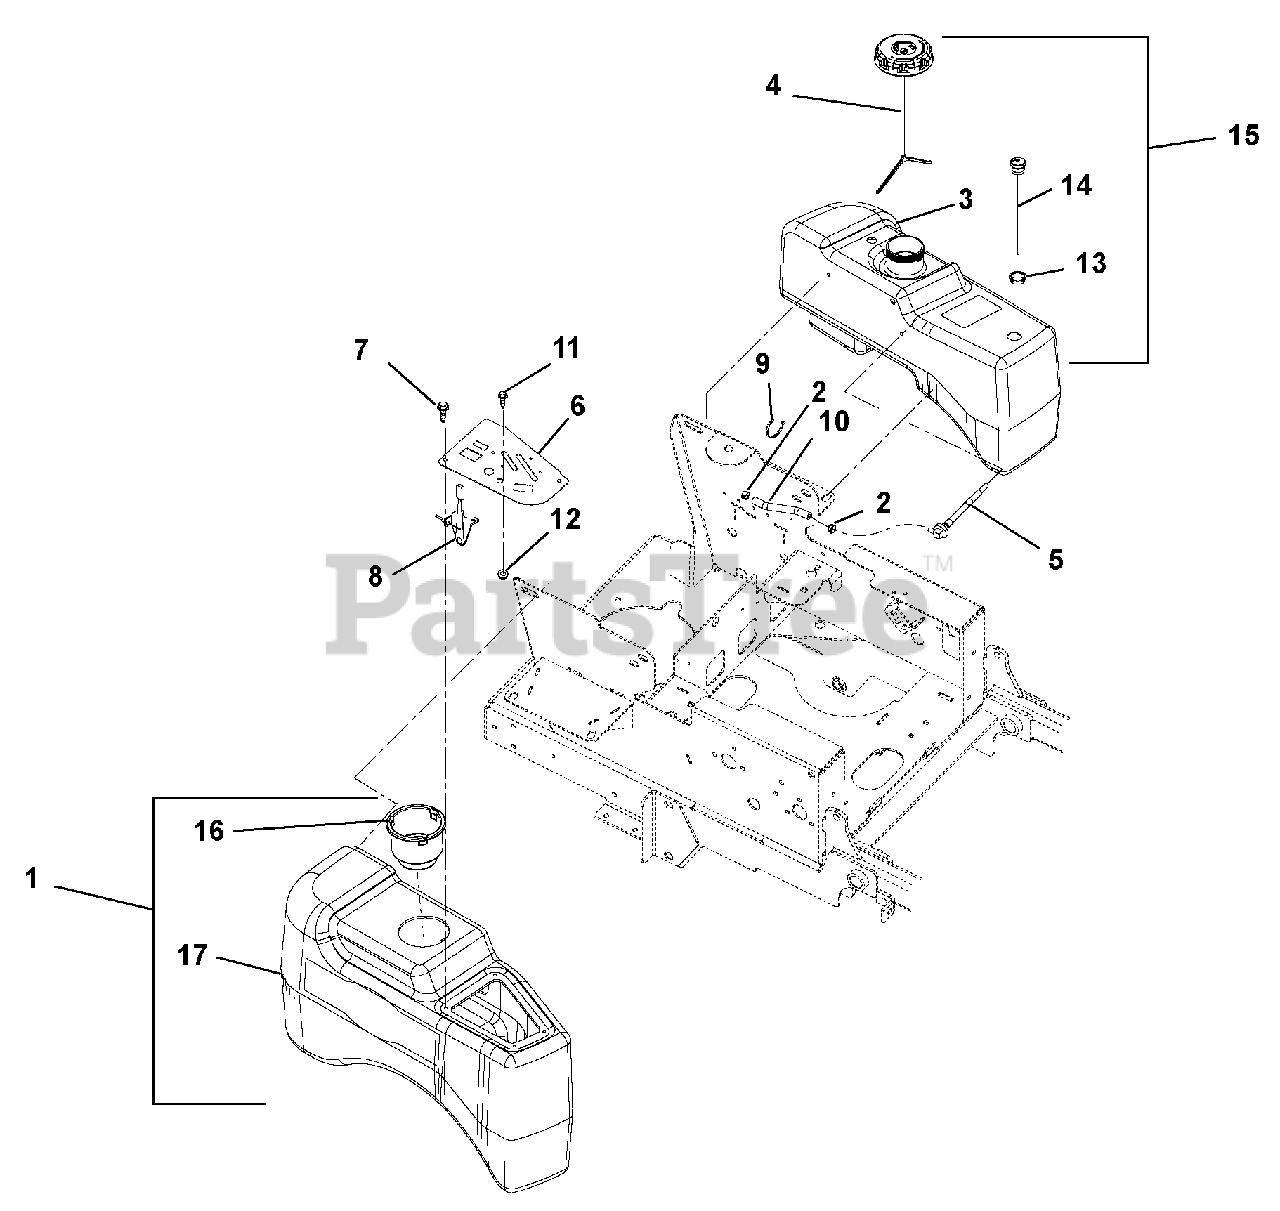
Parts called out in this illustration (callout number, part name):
1	Assembly, Fender with Cupholder (Includes items 16 and 17)
2	Clamp, Fuel Line
3	Tank, Fuel Left Hand
4	Cap, Fuel Vent-in Autolock (991082, 083, 084, 090, 107, 108, 109, 110)
4	Cap, Fuel Non-Vent Autolock (991098, 099, 100, 101)
5	Assembly, Tank Fuel Pick-up
6	Panel, Control
7	Screw, Plastite .25 x 10 x .75 YZ
8	Cable, Control
9	Cable Tie
10	Hose, .25 Low-PERM Bulk Gas
11	Screw, Machine 10-24 x .50 Hex Washer Head
12	Nut, Locking Nylon 10-24 with Insert
13	Grommet, Fuel Gauge
14	Gauge, Remote Fuel 10.0"
15	Assembly, Fuel Tank (Includes items 3, 4, 5, 13, 14 above and items 1, 2 on page 11)
16	Cupholder
17	Fender
